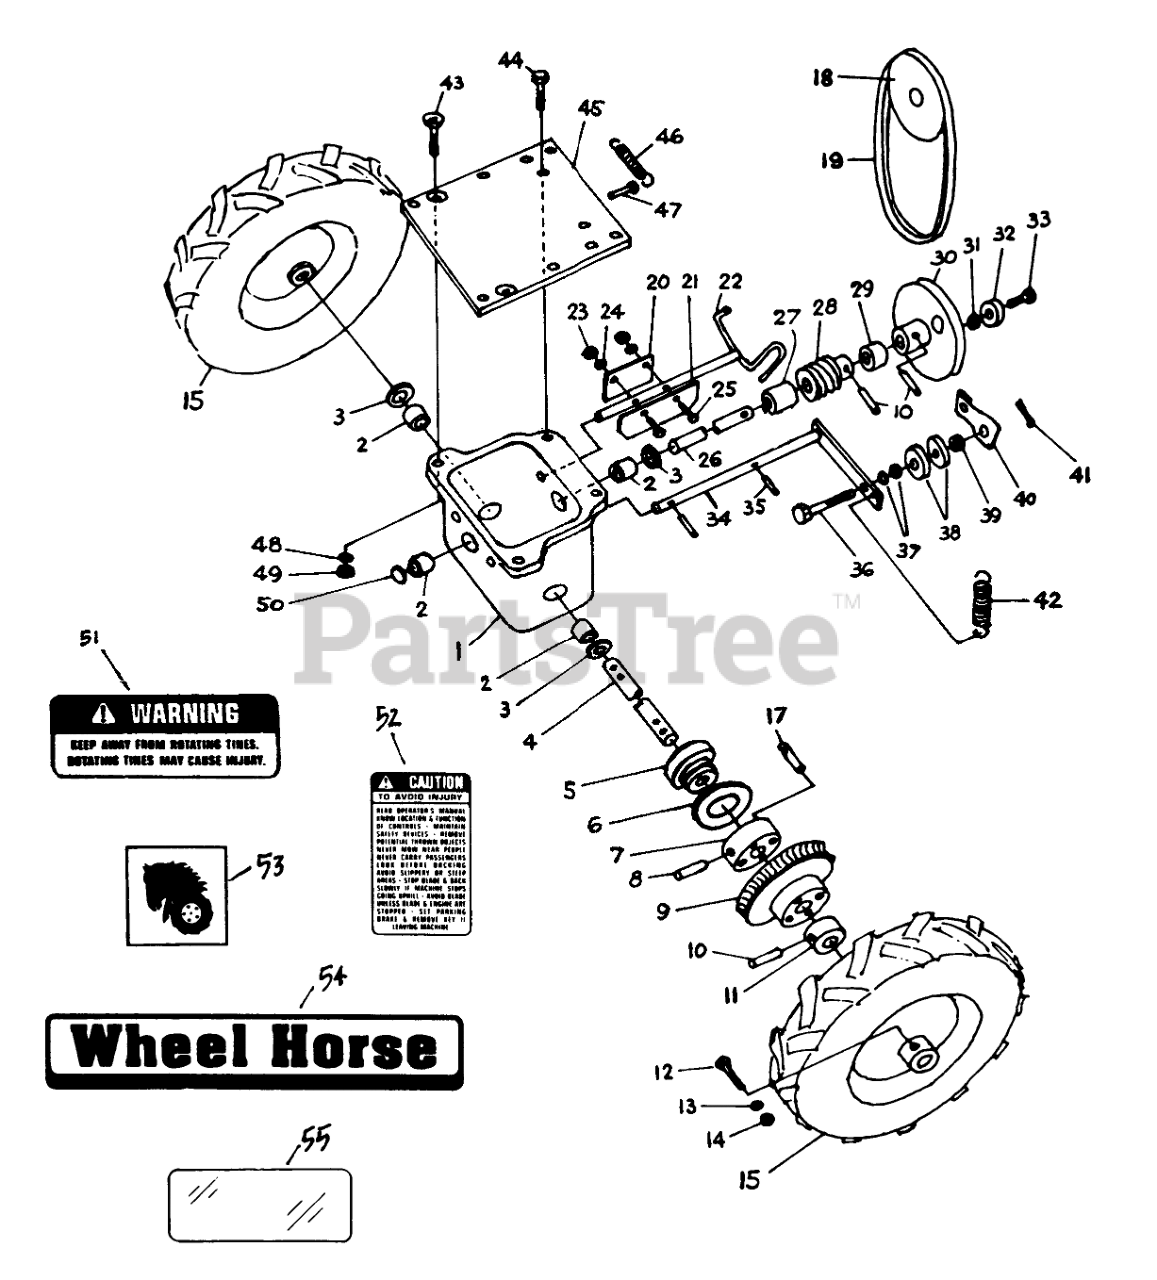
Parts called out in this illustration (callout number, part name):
1	Gear Box
2	Bearing
3	Seal
4	Wheel Shaft
5	Clutch Sleeve
6	Clutch Ring
7	Clutch Collar
8	SPIROL ROLL PIN
9	Worm Gear
10	SPIROL PIN
11	Gear Collar
12	HEX HD CAP SCREW -4
13	Washer
14	Nut
15	Wheel
17	Clutch Pin
18	Engine Pulley
19	BELT-DRIVE
20	CLUTCH IN ACTUATOR
21	Clutch "Out" Actuator
22	Gear Clutch Lever
23	Nut
24	Washer
25	Bolt
26	Worm Shaft
27	Long Worm Spacer
28	Worm
29	Short Worm Spacer
30	Pulley
31	LOCKWASHER
32	BEARING-ECCENTRIC
33	BOLT
34	Idler Lever
35	Pin-Roll
36	Bolt
37	LOCKWASHER
38	Idler Wheel
39	Nut
40	Idler Link
42	SPRING
43	Flathead Screw 5/16-18 x 1 1/4
44	Bolt
45	Top Plate
46	Tension Spring 3/8 x 2 1/2 x .047
47	Groove Pin 1/4 x 1
48	Lockwasher
49	Nut
50	PLUG-WELCH
51	Decal-Warning
52	Decal-Caution
53	DECAL-LOGO
54	5-Speed Decal
55	DECAL-OVERLAY
